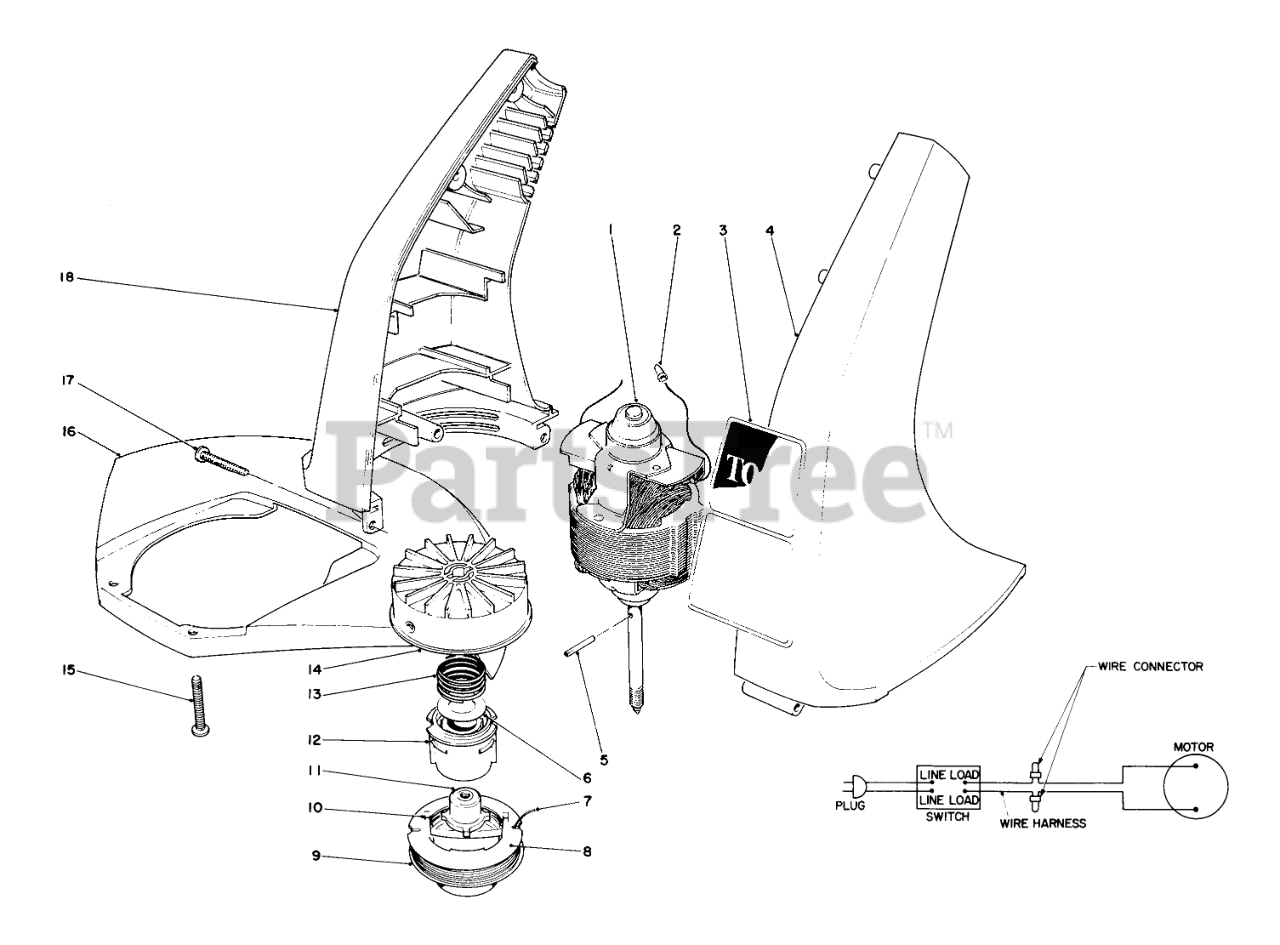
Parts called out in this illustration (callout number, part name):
1	Motor
2	CONNECTOR WIRE JOINT
3	DECAL - 1100 CANADIAN
4	Housing-Left Hand
5	COIL PIN
6	WASHER-FLAT
7	50-, .065" Dia. Cutting Line In Coil
8	Empty Spool
9	50-, .065" Dia. Cutting Line Prewound On Spool
10	SADDLE-SPOOL CAP
11	Driver
12	SPOOL CORE
13	SPRING COMPRESSION
14	DRUM W/EYELET
15	SCREW-PPH
16	Shield
17	Screw
18	R.H. HOUSING, 1100
